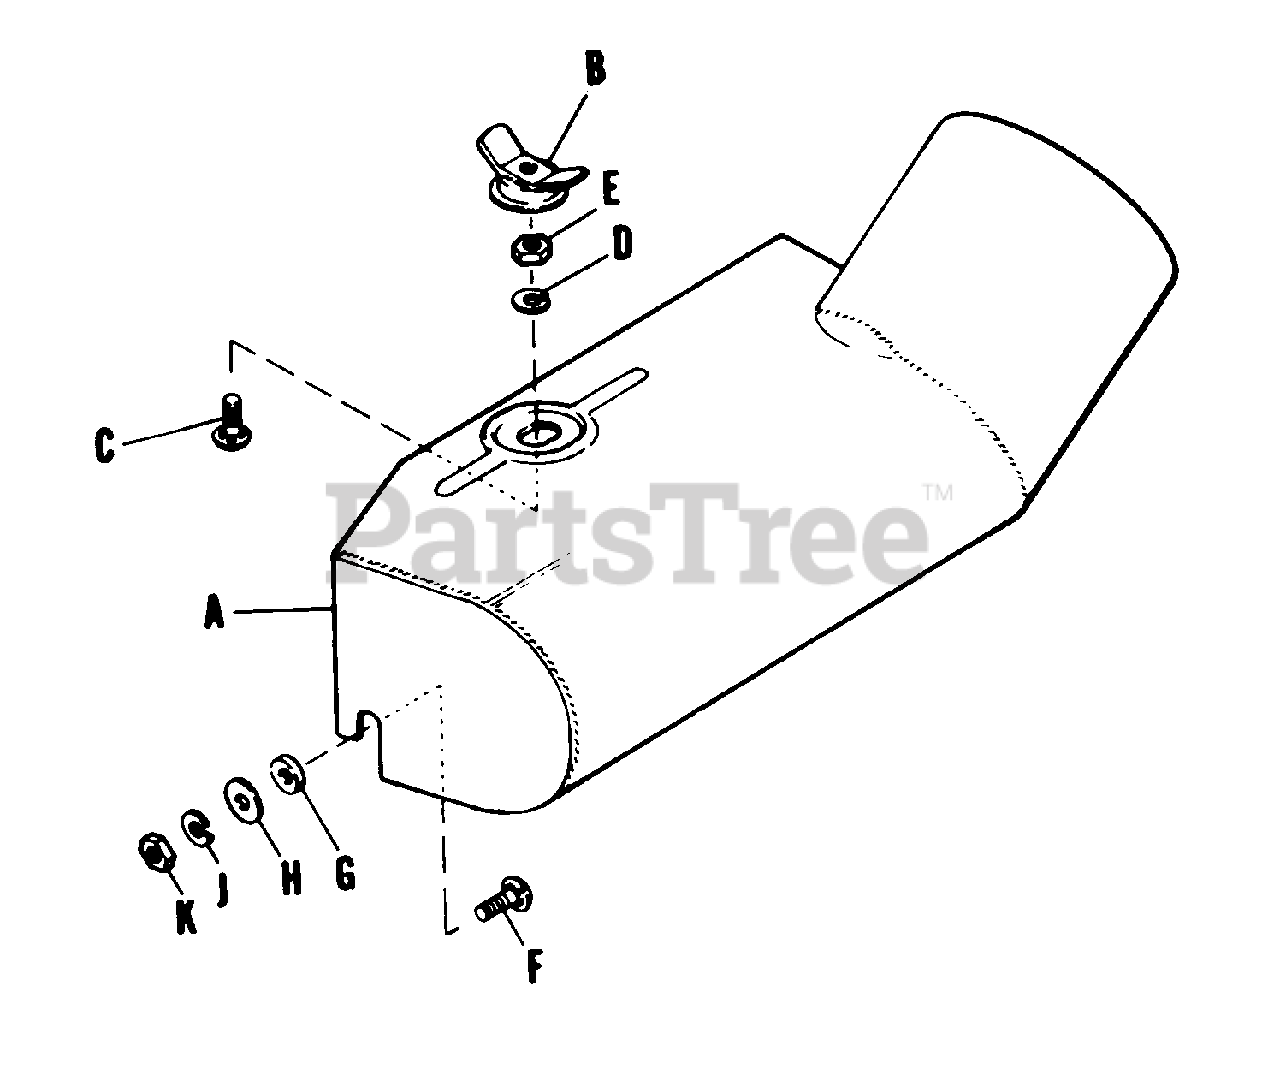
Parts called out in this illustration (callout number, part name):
A	Adaptor Assembly
B	Nut Assembly
C	Carriage Bolt, 3/8"-16 x 1"
D	Lock Washer, 3/8"
E	Nut, Hex, Full, 3/8"-16
F	Carriage Bolt, 3/8"-16 x 1-1/4"
J	Lock Washer, 3/8"
K	Nut, Hex, Full, 3/8"-16
